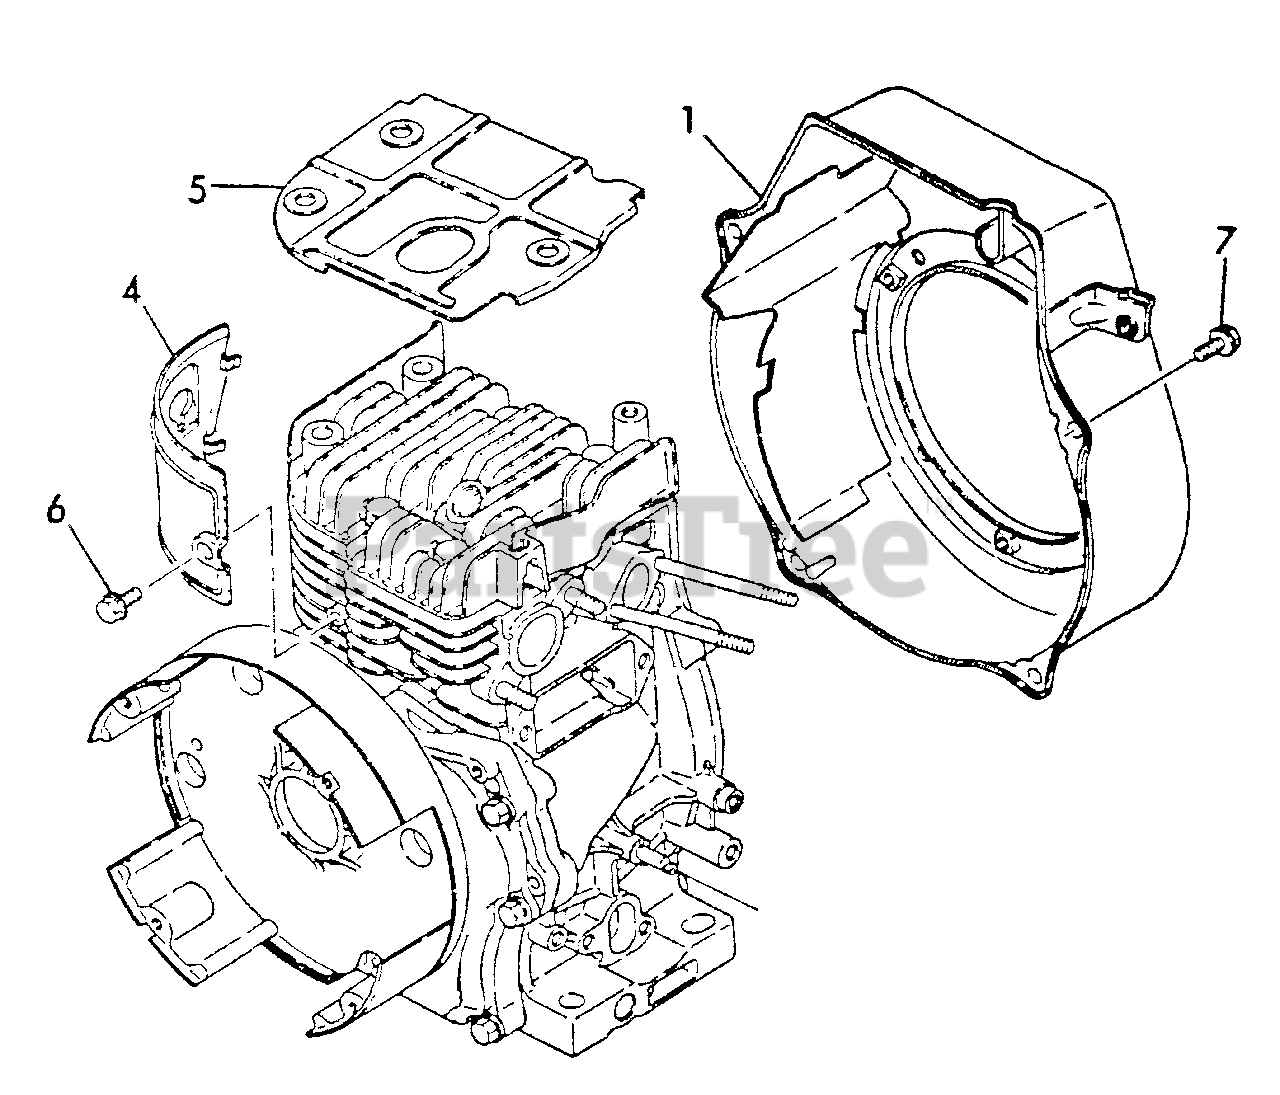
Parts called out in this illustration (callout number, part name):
1	CASE, FAN
4	PLATE
5	COVER, HEAD
6	BOLT - 6X8 -- PLATED
7	BOLT - 6X8 -- PLATED
